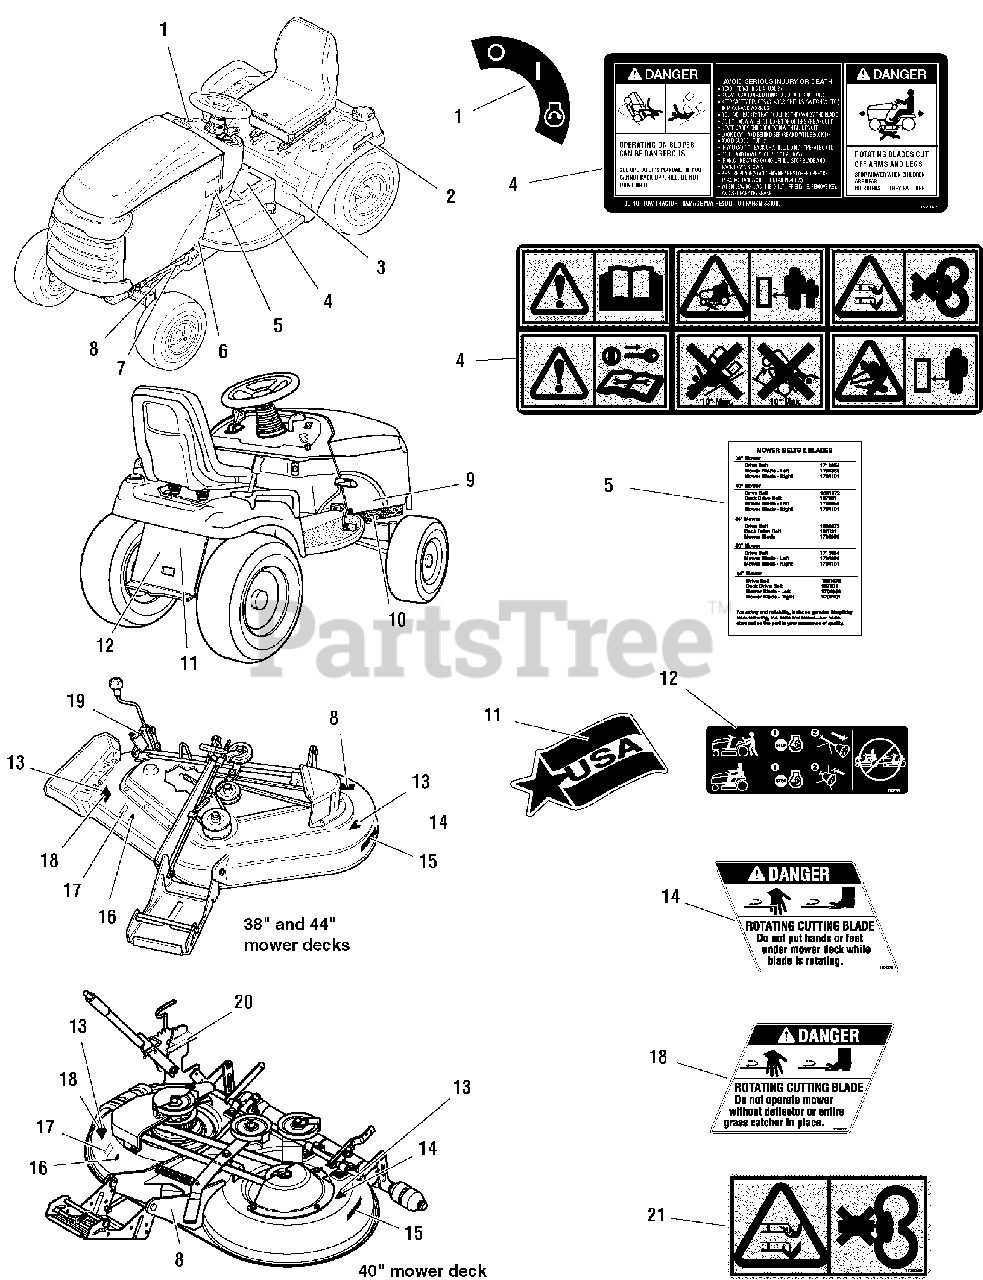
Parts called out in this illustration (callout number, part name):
1	DECAL, Ignition Switch Symbols, White/Black
2	DECAL, Automatic Control Traction
3	DECAL, 16HP
4	DECAL, Tunnel Cover, Danger Slopes/Blades
4	DECAL, Tunnel Cover, Danger Slopes/Blades, (Export)
5	DECAL, Drive Belts, Mower Blades (56 Tooth Sprocket Mower)
5	DECAL, Drive Belts & Mower Blades (38 Tooth Sprocket Mower)
6	DECAL, Protective Sticker
7	LABEL, Decibel, Power Mass (Export)
8	DECAL, I.D. Plate
9	DECAL, Powered by HONDA
10	DECAL, Patent
11	DECAL, USA Logo Stars & Stripe
12	DECAL, Transmission Release Valve
13	DECAL, Danger Rotating Blades (Export)
14	DECAL, Danger Do Not Put Hands/Feet in Mower
15	DECAL, Free Floating Mower, Silver
16	DECAL, OPEI Certified
17	DECAL, 38", Silver on Black with Stripe
17	DECAL, 40", Silver on Black with Stripe
17	DECAL, 44", Silver on Black with Stripe
18	DECAL, Danger Do Not Operate Without Deflector
19	DECAL, Height of Cut, 38" & 44"
20	DECAL, Height of Cut, 40"
